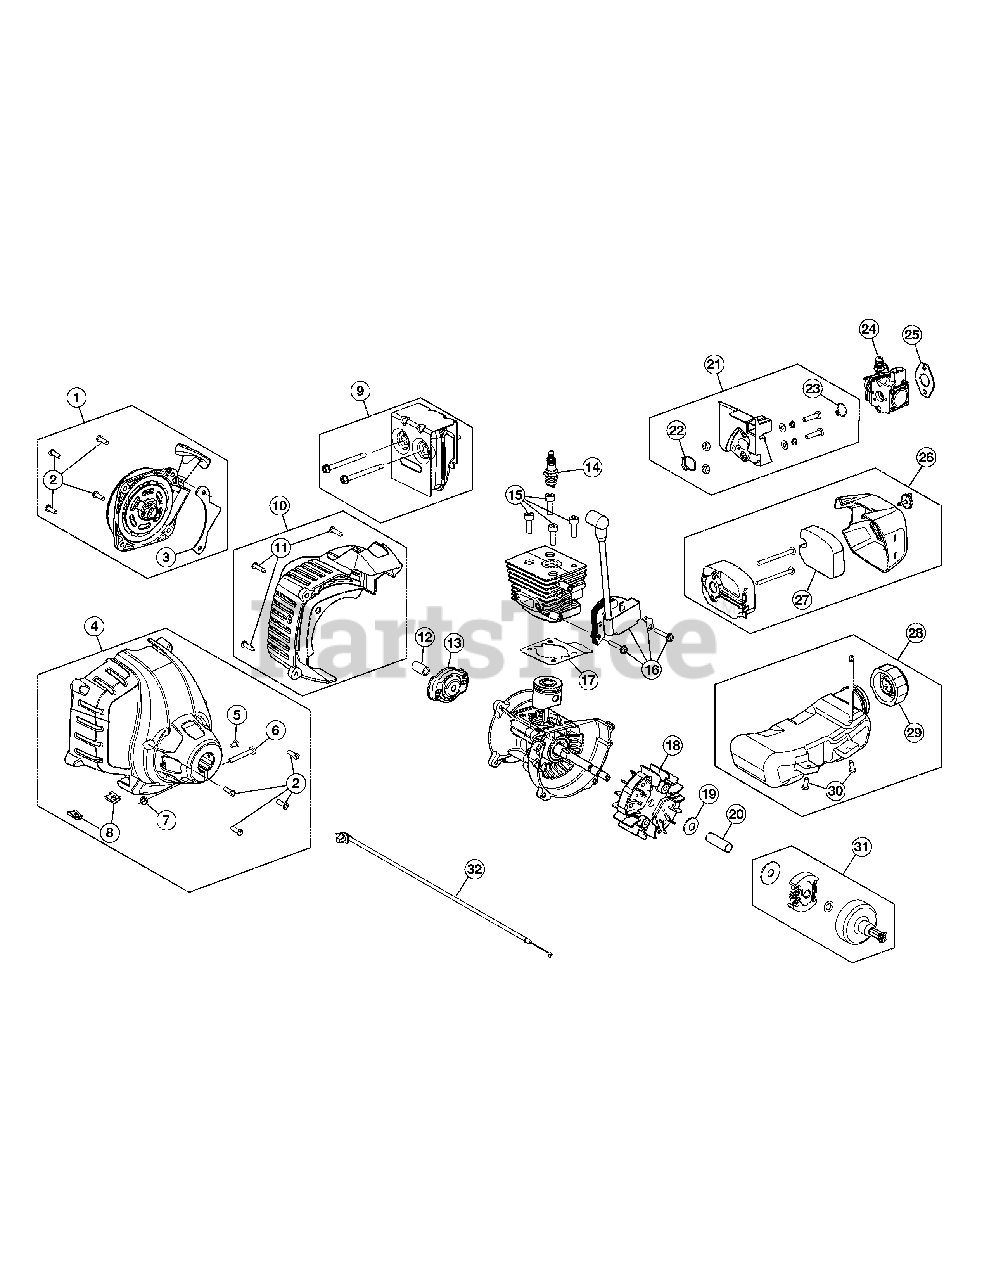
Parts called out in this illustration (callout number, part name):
1	Starter Assembly (Incl. 2 & 3)
2	Starter Screw
3	Starter Assembly Guard (Incl. 2)
4	Clutch Cover Assembly (Incl. 2, 5 - 8)
5	Anti-rotation Screw
6	Clamp Screw
7	Clamp Nut
8	U-shaped Nut
9	Muffler Assembly
10	Rear Engine Cover (Incl. 11)
11	Cover Screw
13	Pawl Assembly
14	Spark Plug
15	Cylinder Bolt
16	Module Assembly
17	Cylinder Gasket
18	Flywheel Assembly
21	Insulator Assembly (Incl. 22 and 23)
22	Insulator O-Ring
23	Carburetor O-Ring
24	Carburetor
25	Carburetor Gasket
26	Air Cleaner Assembly (Incl. 27)
27	Air Cleaner Filter
28	Fuel Tank Assembly (Incl. 18 and 19)
30	Fuel Tank Screw
31	Clutch Assembly
32	Lead Wires
